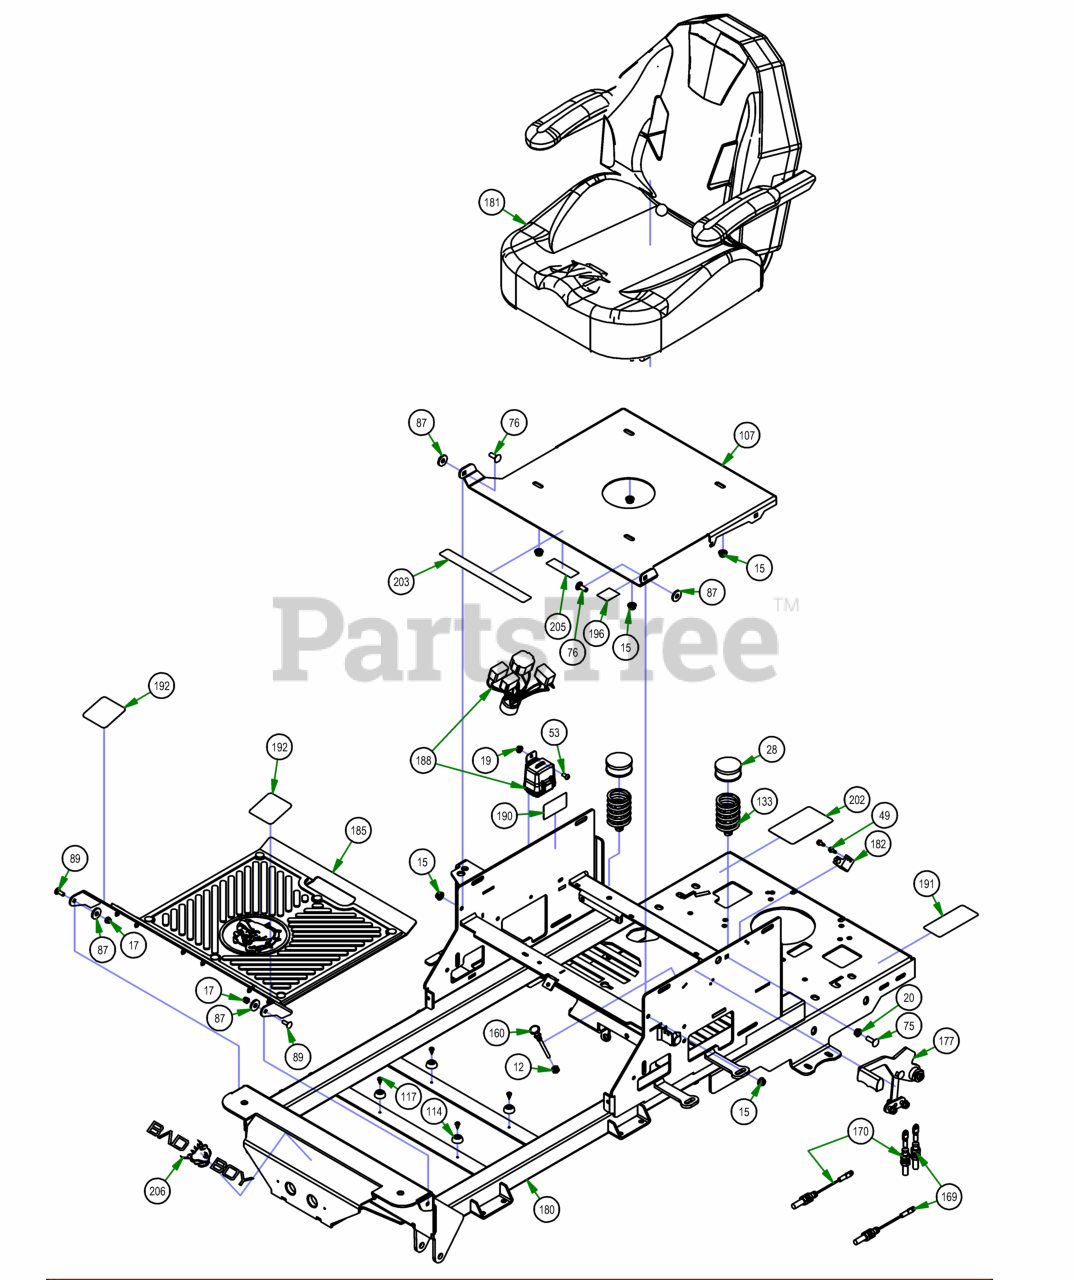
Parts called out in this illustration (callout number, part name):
12	3/8-24 HEX NUT ZINC YELLOW
15	5/16-18 NYLON INSERT FLANGE LOCKNUT ZINC
17	1/4-20 NYLON INSERT LOCKNUT ZINC
19	1/4-20 HEX SERRATED FLANGE NUT HARD/ZINC
20	5/16-18 HEX SERRATED FLANGE NUT HARD/ZINC
28	Spring Cap Cover
49	12-24 X 1/2 HEX WASHER UNLSOT F TCS ZINC
53	1/4-20 X 1/2 BUTTON SOCKET CAP SCREW 18-8 STAINLESS STEEL
75	5/16-18 X 1 CARRIAGE BOLT (GR.8) ZINC
76	5/16-18 X 7/8 CARRIAGE BOLT ZINC
87	.360 ID X .983 OD X .120 THICK FLAT WASHER NYLON
89	1/4-20 X 3/4 CARRIAGE BOLT (GR.5) ZINC
107	Seat Plate 2016
114	Button Bumper
117	10-16 X 1/2 PAN PHIL TEK/3 CLIMASEAL OR ACF-SILVER COATED
133	Seat Spring Assembly
169	2021 Load Balanced Brake Cable 1
170	2021 Load Balanced Brake Cable 2
177	2021 Load Balanced Brake Handle Assembly
180	2021 ZT Frame - Painted
181	2021 ZT Elite Seat
182	Safety Switch
185	2020 Maverick and 2021 ZT Elite Floorboard Assembly
188	Wiring Harness
190	ANSI Decal BZ60KT745P
191	EPA Build Date Punch Label
192	2018 Maverick/2021 ZT Anti-Skid Steering Control Decals
196	2018 MZ/Magnum/ZT/MAV/Comp Out Brake Decal
202	Pump Belt Route Decal-Pump Plate
203	Outlaw Warning Decal
205	Not For Sale In California
206	Flying Bulldog Front Bumper Decal
